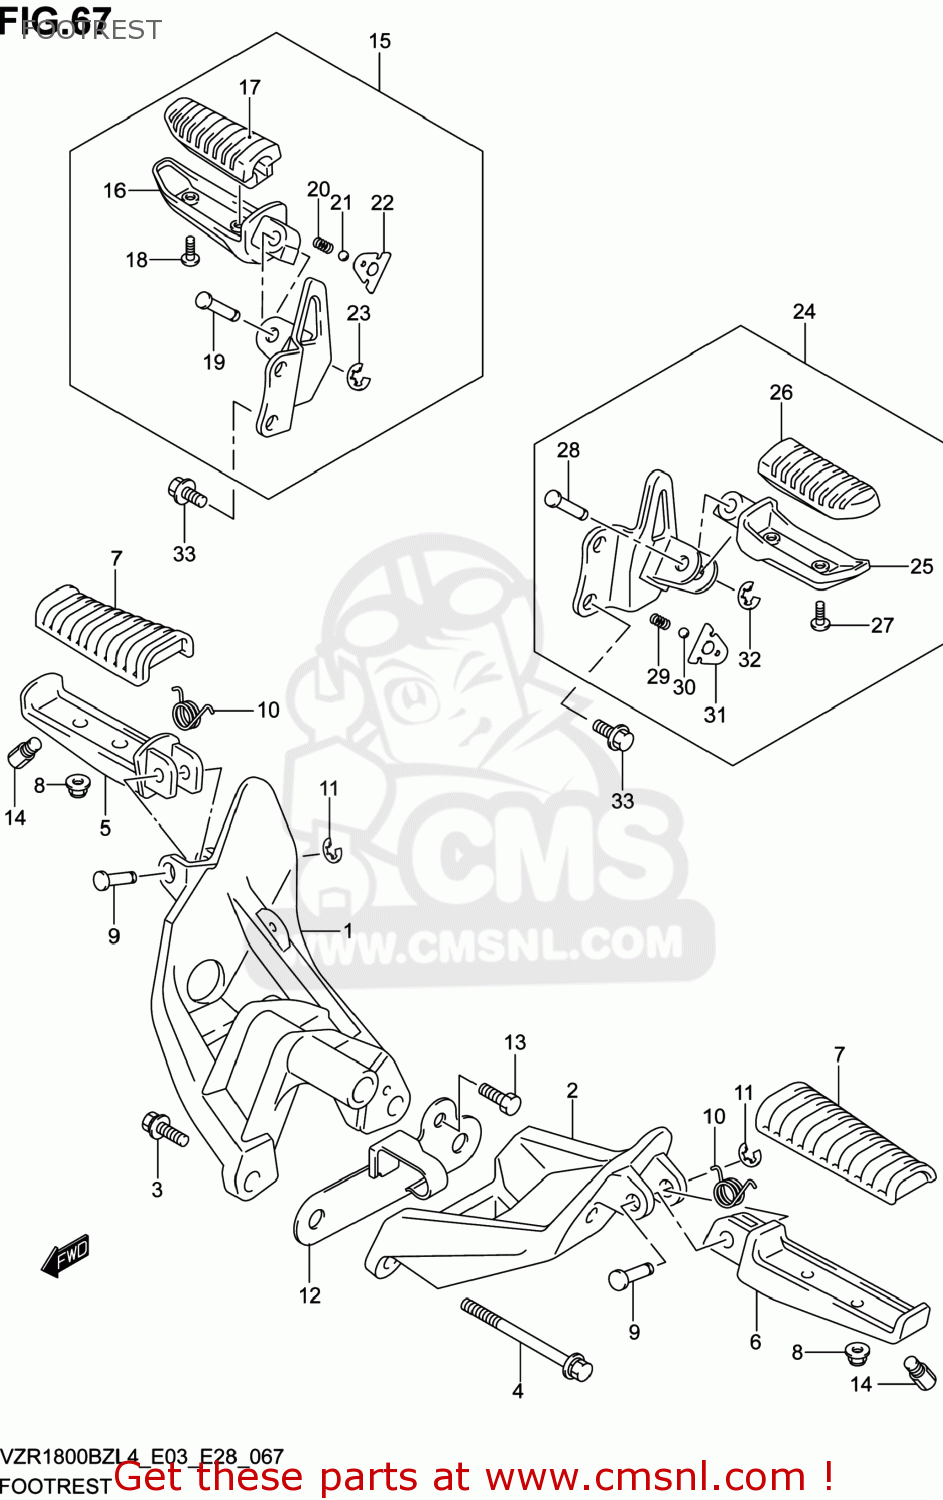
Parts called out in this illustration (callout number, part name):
1	BRACKET,FR FOOTREST,R
2	BRACKET,FR FOOTREST,L
3	BOLT(10X28)
4	BOLT(10X85)
5	BAR,FR FOOTREST,R
6	BAR,FR FOOTREST,L
7	RUBBER,FR FOOTREST
8	NUT
9	PIN
10	SPRING
11	E RING
12	PLATE,FOOTREST BRACKET
13	BOLT
14	BOLT,BANK SENSOR
15	FOOTREST ASSY,PILLION,R
16	BAR,PILLION FOOTREST,R
17	RUBBER,FOOTREST
18	SCREW
19	PIN
20	SPRING
21	BALL
22	PLATE,PILLION,R
23	E RING
24	FOOTREST ASSY,PILLION,L
25	BAR,PILLION FOOTREST,L
26	RUBBER,FOOTREST
27	SCREW
28	PIN
29	SPRING
30	BALL
31	PLATE,PILLION,R
32	E RING
33	BOLT(8X16)
